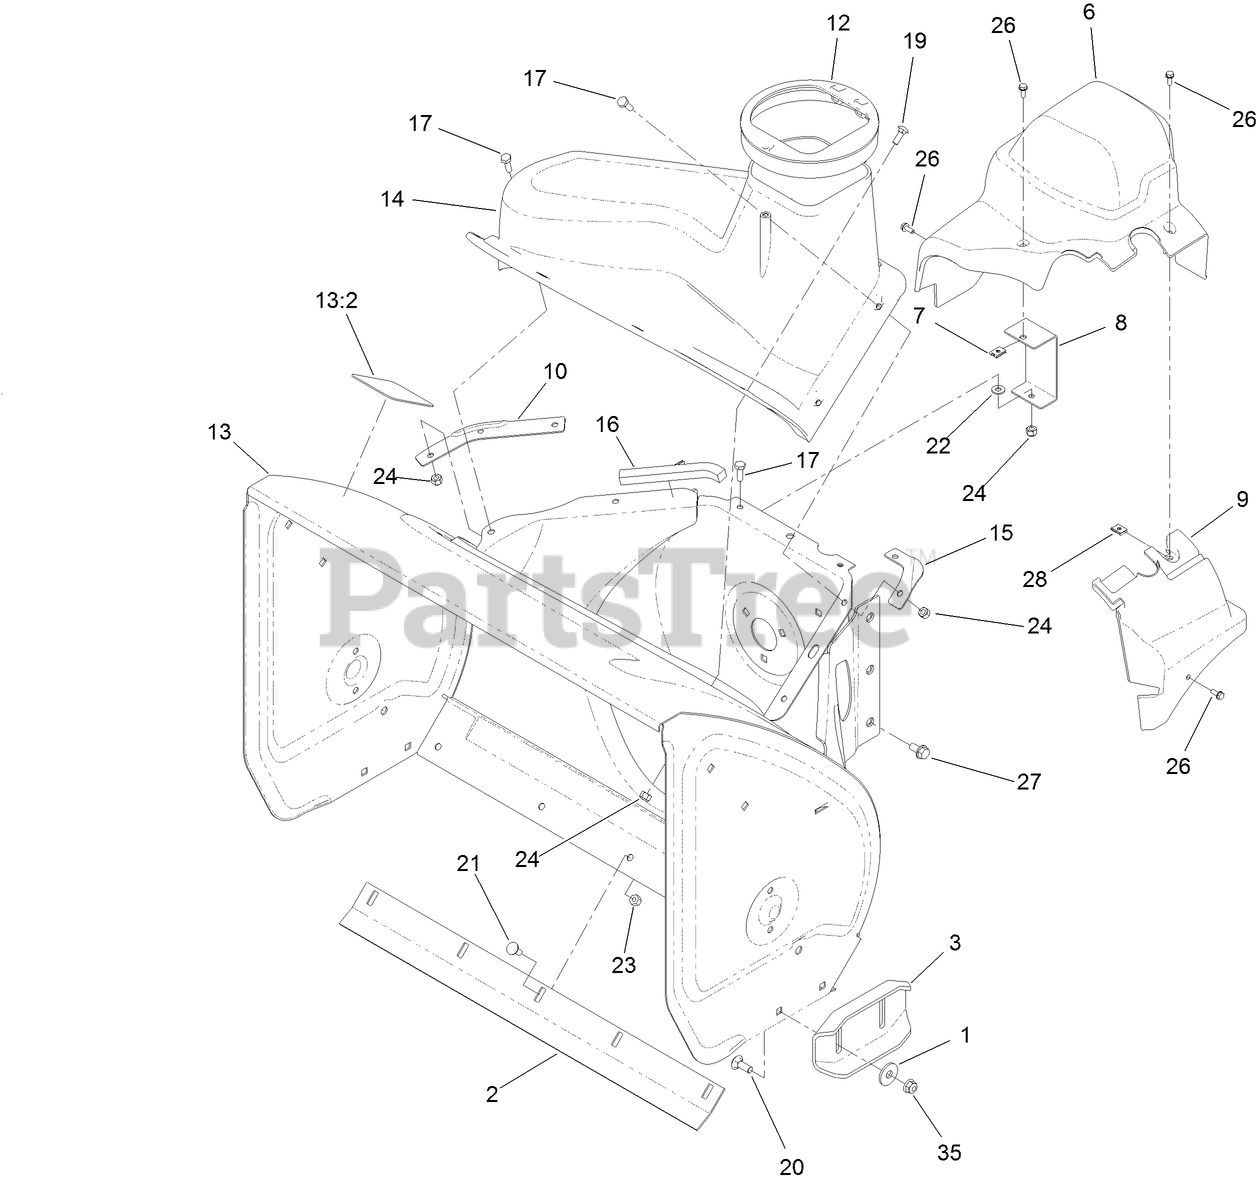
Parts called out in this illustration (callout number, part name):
1	WASHER-FLAT
2	SCRAPER-FIXED
6	COVER-BELT
7	NUT-SPEED
8	BRACKET-COVER, CLIP NUT
9	COVER-EXTENSION, BELT
10	SEAL-FLANGE, COVER
12	GUIDE-CHUTE
13	HOUSING-AUGER, 28 INCH
13:2	DECAL-DANGER
16	SEAL-HOUSING
17	SCREW-HH
19	BOLT-CARR
20	BOLT-CARR
21	BOLT-CARR
22	WASHER-FLAT
23	NUT-HEX
24	NUT-HEX
26	SCREW-HWH
27	SCREW-HWHTF
28	NUT-SPEED
35	NUT-HF
